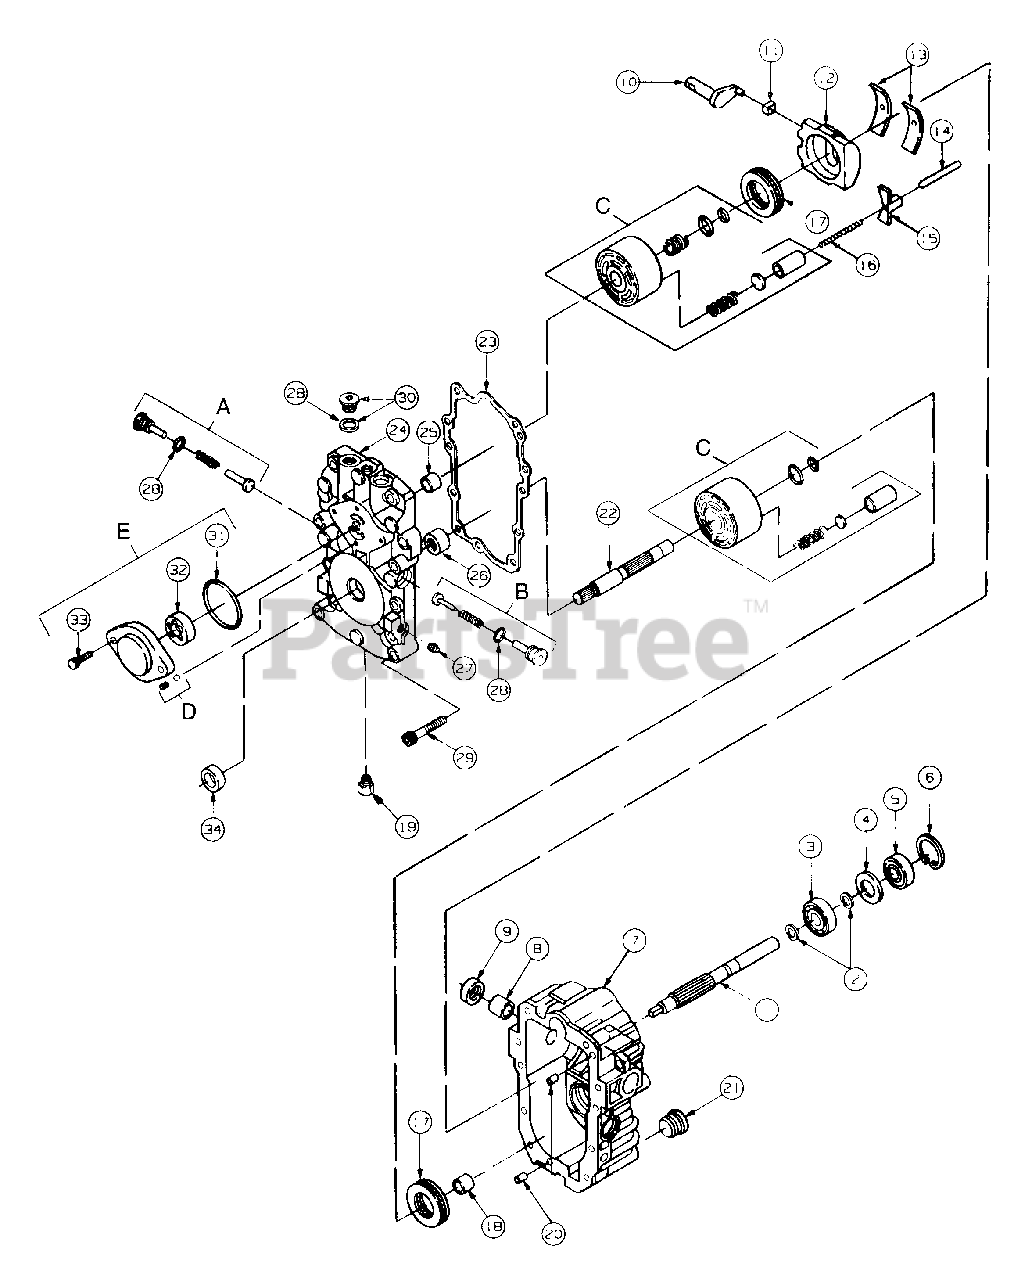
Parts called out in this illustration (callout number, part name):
1	Shaft, Pump
2	Ring, Retaining
3	Bearing, Ball
4	Spacer
5	Seal, Lip
6	Ring, Retaining
7	Housing Assy
8	Bearing, Journal
9	Seal, Lip
10	Arm, Trunnion
11	Guide, Slot
13	Bearing, Cradle
14	Pin, Leveler
15	Leveler, Swashplate
16	Spring, Leveler
17	Bearing, Thrust
18	Bearing, Journal
22	Shaft, Motor
23	Gasket, Center Section
24	Center Section Assy
25	Bearing, Journal
26	Bearing, Needle
28	O-Ring
29	Screw, Socket Hd
31	O-Ring
32	Gerotor Assy
33	Screw, Socket Hd
34	Not Used In This Application
A	Kit, Check Valve
B	Kit, Orificed Check Valve
C	Kit, Cylinder Block
D	Kit, Charge Relief Valve
E	Kit, Charge Pump
